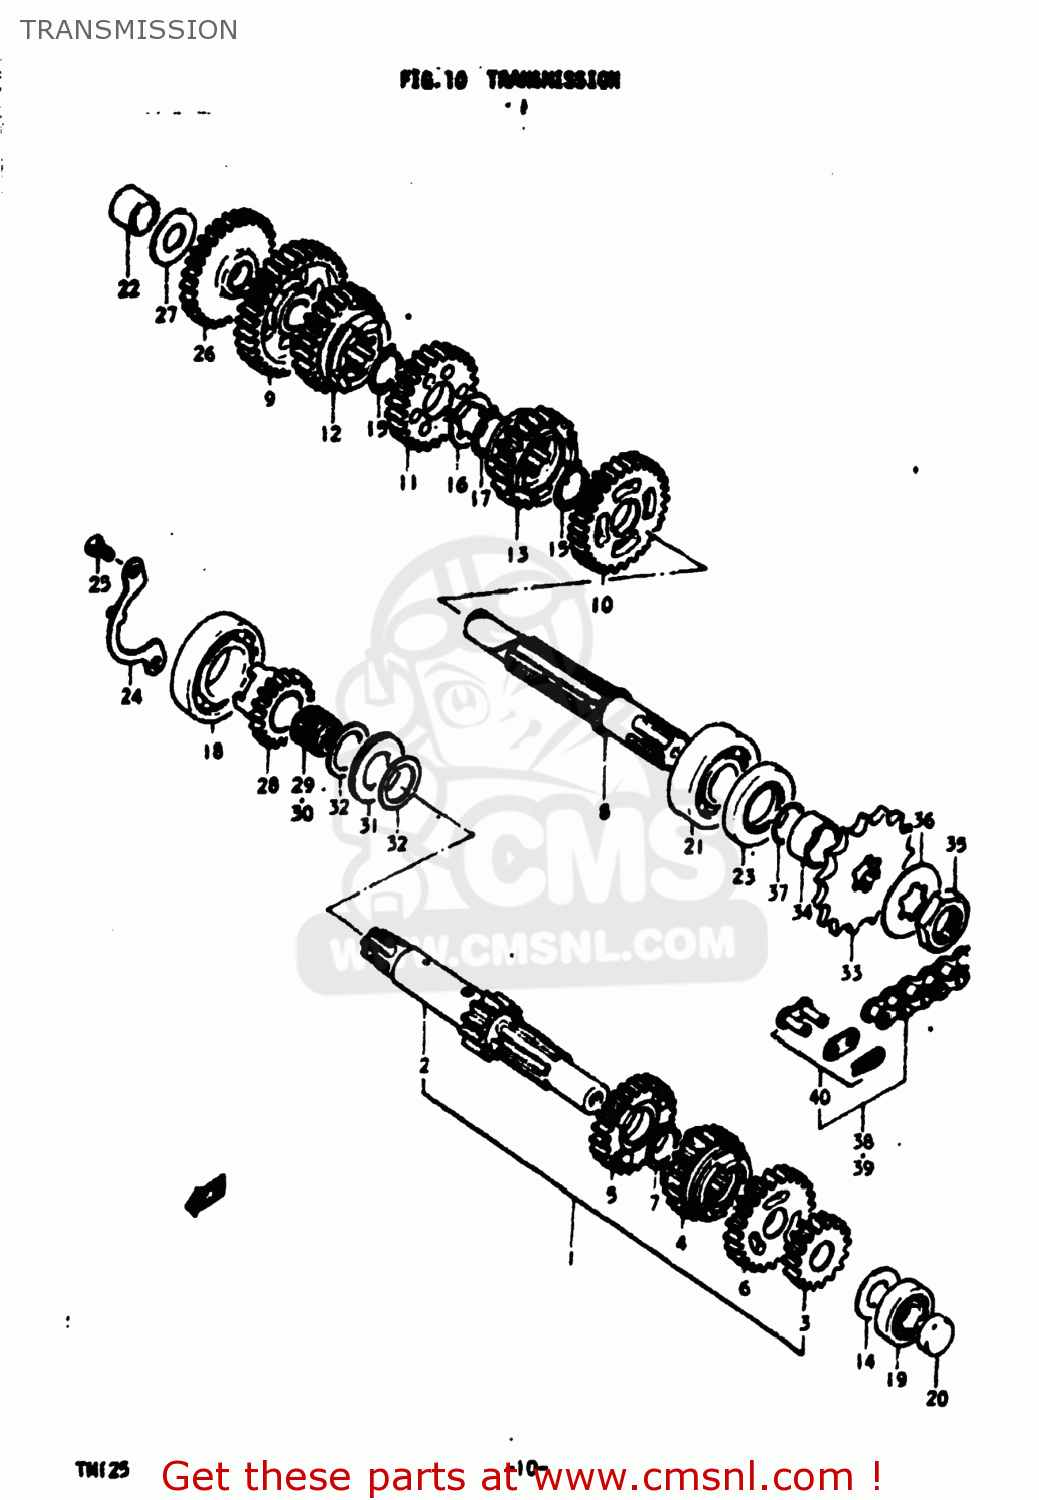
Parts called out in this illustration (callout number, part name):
1	SHAFT,COUNTER
2	SHAFT,COUNTER
3	GEAR,SECOND DRIVE
4	GEAR,THIRD DRIVE
5	GEAR,FOURTH DRIVE
6	GEAR,FIFTH DRIVE
7	CIRCLIP
8	SHAFT,DRIVE
9	GEAR,FIRST DRIVEN
10	GEAR,SECOND DRIVEN
11	GEAR,THIRD DRIVEN
12	GEAR,FOURTH DRIVEN
13	GEAR,FIFTH DRIVEN
14	WASHER
15	CIRCLIP
16	WASHER
17	CIRCLIP
18	BEARING, RH
19	BEARING
20	PLUG
21	BEARING
22	BUSHING
23	OIL SEAL (25X44X7)
24	RETAINER,CNTR SHAFT BEARING
25	SCREW
26	GEAR,KICK STARTER IDLE
27	WASHER
28	GEAR,KICK STARTER DRIVE
29	BEARING
30	BEARING(19.2X23.2X19)
31	BEARING(21X32X2.85)
32	WASHER(21X30X0.8)
33	SPROCKET,ENGINE
34	SPACER(20X25X12.5)
35	NUT
36	WASHER,LOCK
37	O RING(D:1,ID:19.5)
38	CHAIN ASSEMBLY,DRIVE
39	CHAIN ASSEMBLY,DRIVE
40	JOINT ASSEMBLY,CHAIN
